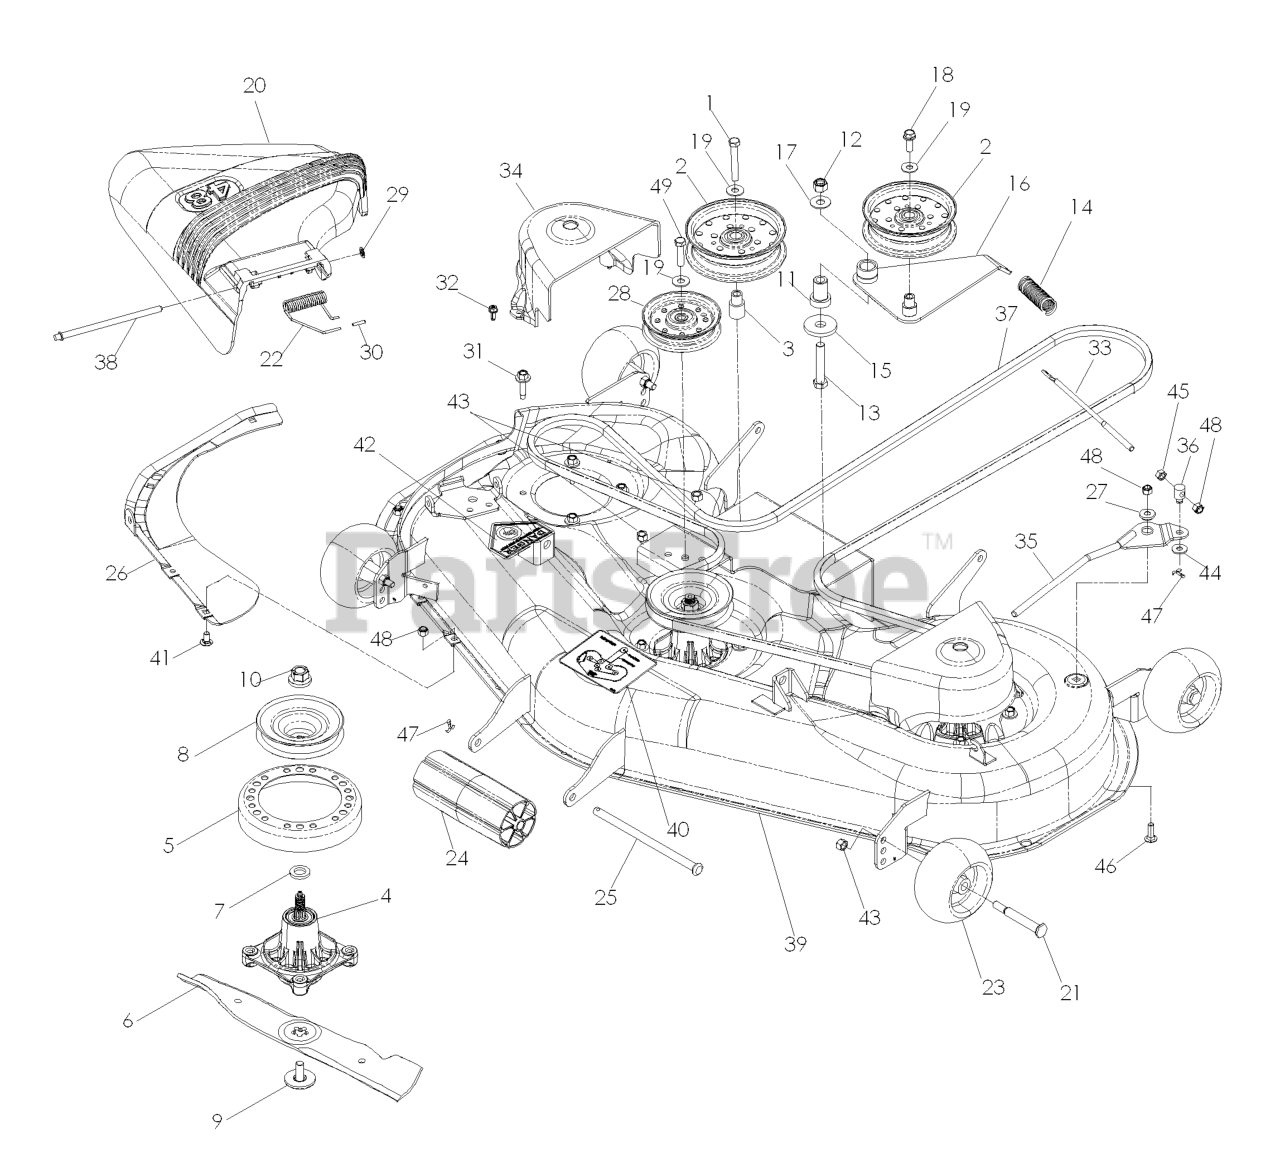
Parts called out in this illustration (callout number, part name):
1	SCREW 3/8C X 2 3/4 HEX CAP
2	IDLER PULLEY
3	IDLER BUSHING
4	CUTTER HOUSING
5	STRIPPER-ROUND-UNIVERSAL
6	BLADE-HIGH LIFT/48"
7	WASHER-SPACER
8	DRIVEN PULLEY-48"
9	BLADE BOLT ASSY-7/16" TB REPL
10	LOCKNUT - 9/16
11	IDLER SPINDLE
12	NUT 1/2-13 HEX NYLOC ZD
13	SCREW, 1/2C X 3 HEX CAP
15	WASHER, SUPPORT
16	DECK IDLER ARM
17	WASHER 1/2 FLAT
18	4CS 3/8C X 1 SERRATED HEAD
19	WASHER 5/16 FLAT
20	DISCHARGE CHUTE
21	SHOULDER BOLT 1/2X2-5/8 ZD SPE
22	TORSION SPRING
23	GAUGE WHEEL
24	NOSE ROLLER-48"
25	NOSE ROLLER ROD
26	VORTEX MOWER BAFFLE
27	PIVOT BUSHING
28	FLAT IDLER PULLEY
29	PUSH NUT
30	CAP-SLEEVE
31	WASHER HEAD SCREW
32	SCREW- 1/4-20 X 5/8
33	TENSION RELIEF LINKAGE
34	BELT SHIELD
35	TENSION RELIEF LEVER BLK
37	BELT, DECK
38	ROD, HINGE
39	DECK SVC W/DECALS HUSQ ORANGE
40	DECAL, BELT ROUTING
41	CARRIAGE BOLT 5/16C X 5/8"
42	DECAL, CPSC
43	NUT 3/8-16 NYLOC
44	WASHER 3/8 SAE FLAT
45	NUT 5/16C HEX
46	RHSNB 5/16C X 1
47	RP_COTTER PIN 1/8 X 3/4
48	NUT 5/16 NYLOC
49	HCS 3/8-16 X 1 3/4 GR5
